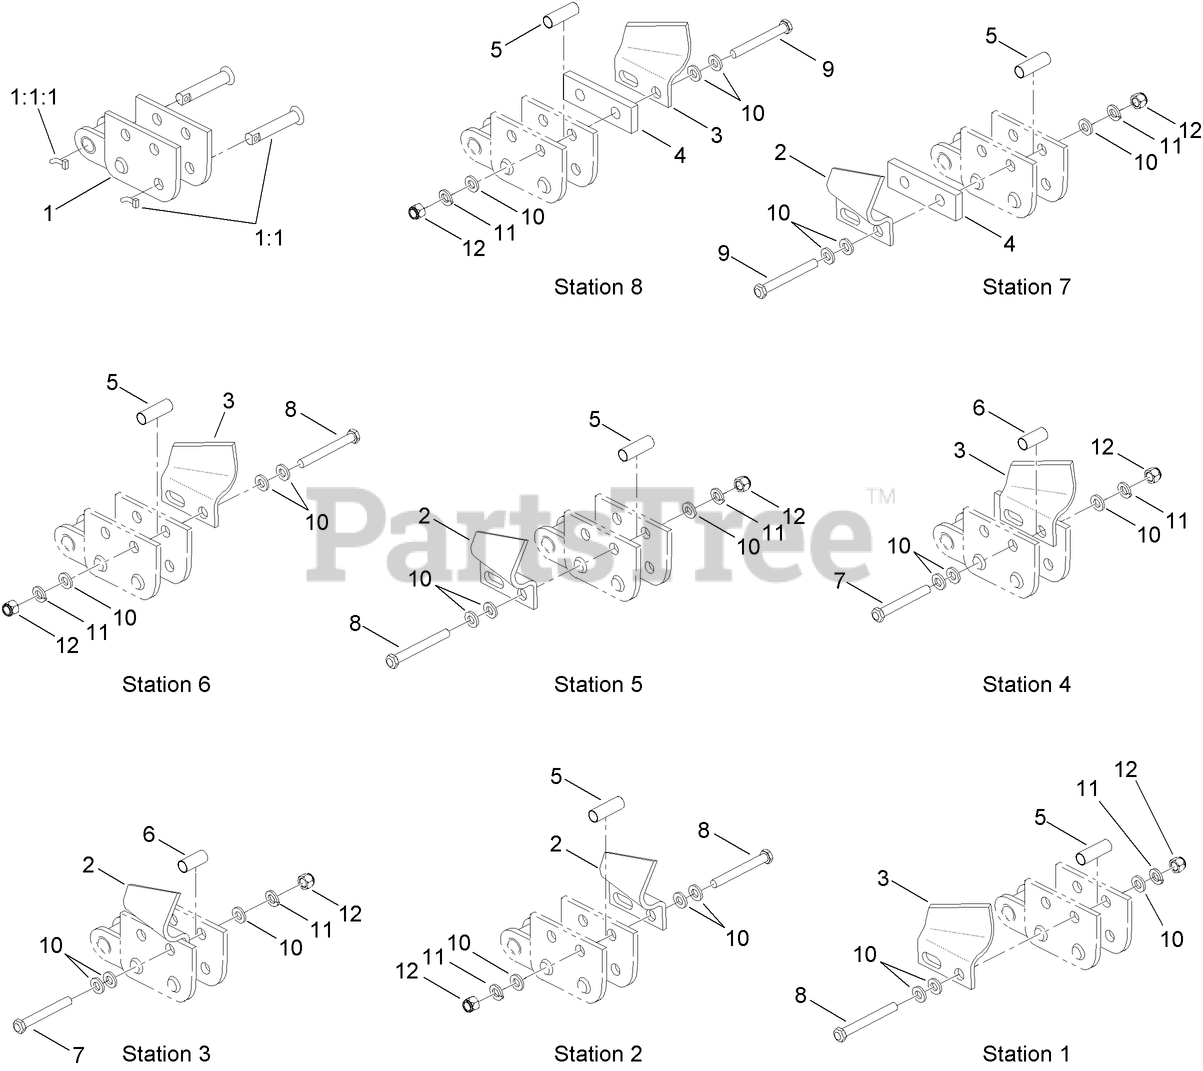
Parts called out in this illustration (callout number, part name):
1	CHAIN REPAIR LINK ASM
1:1	NOTCHED PIN AND KEEPER ASM
1:1:1	PIN-KEEPER
2	CUTTER-CUP, RH
3	CUTTER-CUP, LH
4	SPACER-FLAT
5	SPACER-TUBE, OUTSIDE MOUNT
6	SPACER-TUBE, INSIDE CUP MOUNT
7	BOLT-HH
8	BOLT-HH
9	BOLT-HH
10	WASHER-FLAT
11	WASHER-LOCK
12	NUT-LOCK
